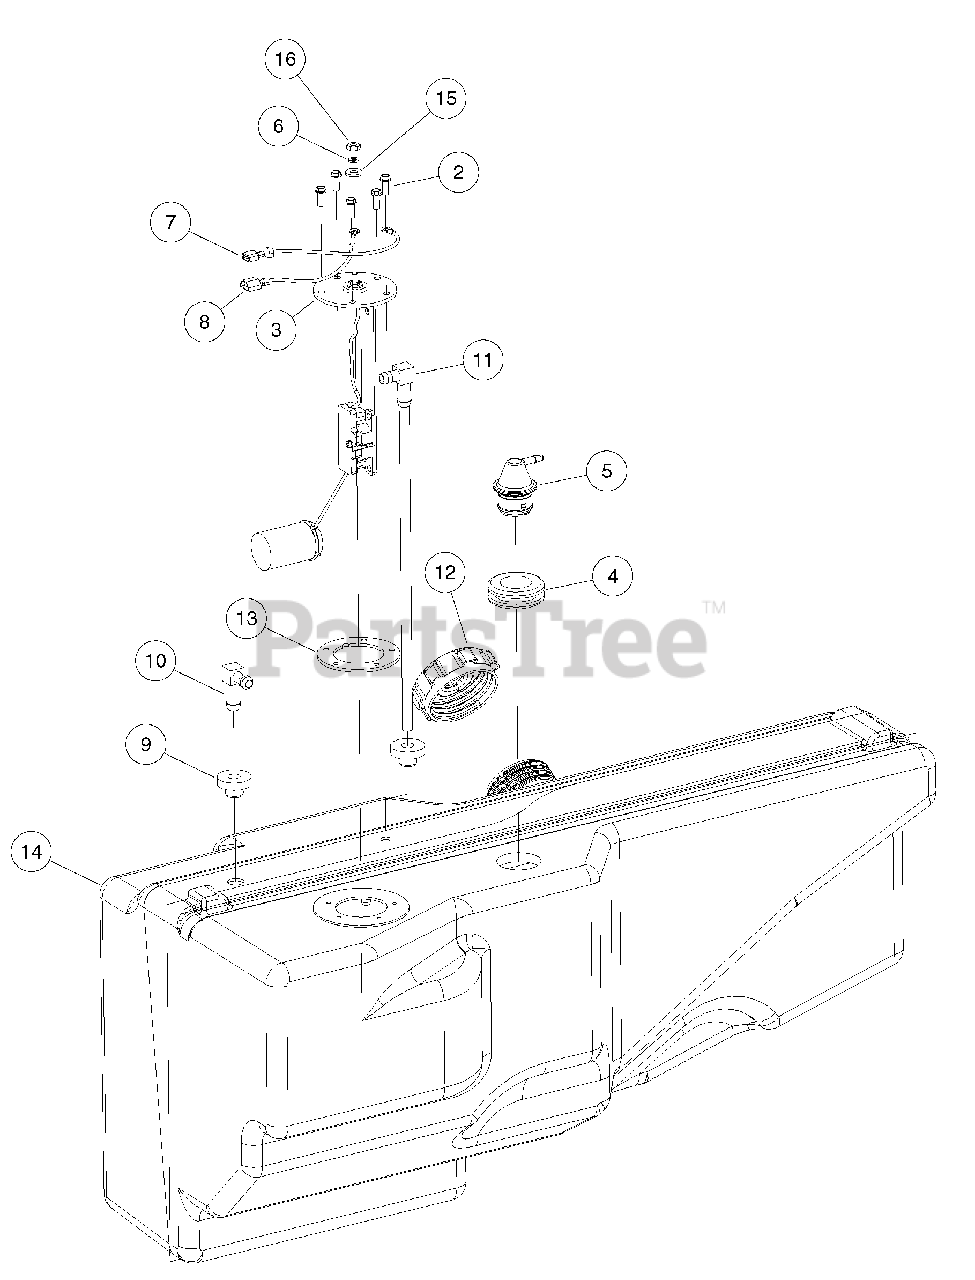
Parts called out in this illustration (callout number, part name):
1	Asm, Tank, Fuel, Diesel, 4x4
2	Screw, #10-16 Hex-Head Hi-Lo
3	Sending Unit, Fuel Level
4	Insulation Grommet
5	Vent, Fuel Tank
6	Washer, #10 Split Lock
7	Wire Asm, Blk, 170mm
8	Wire Asm, Org, 170mm
9	Bushing, Line, Return
10	Elbow, 90 Barbed
11	Pickup Tube, Fuel
12	Cap, Fuel (Diesel)
13	Gasket, Rubber
14	Tank, Fuel, Diesel, 4x4
15	Washer, #10 Type A Flat
16	Nut, #10-32 Brass Hex
